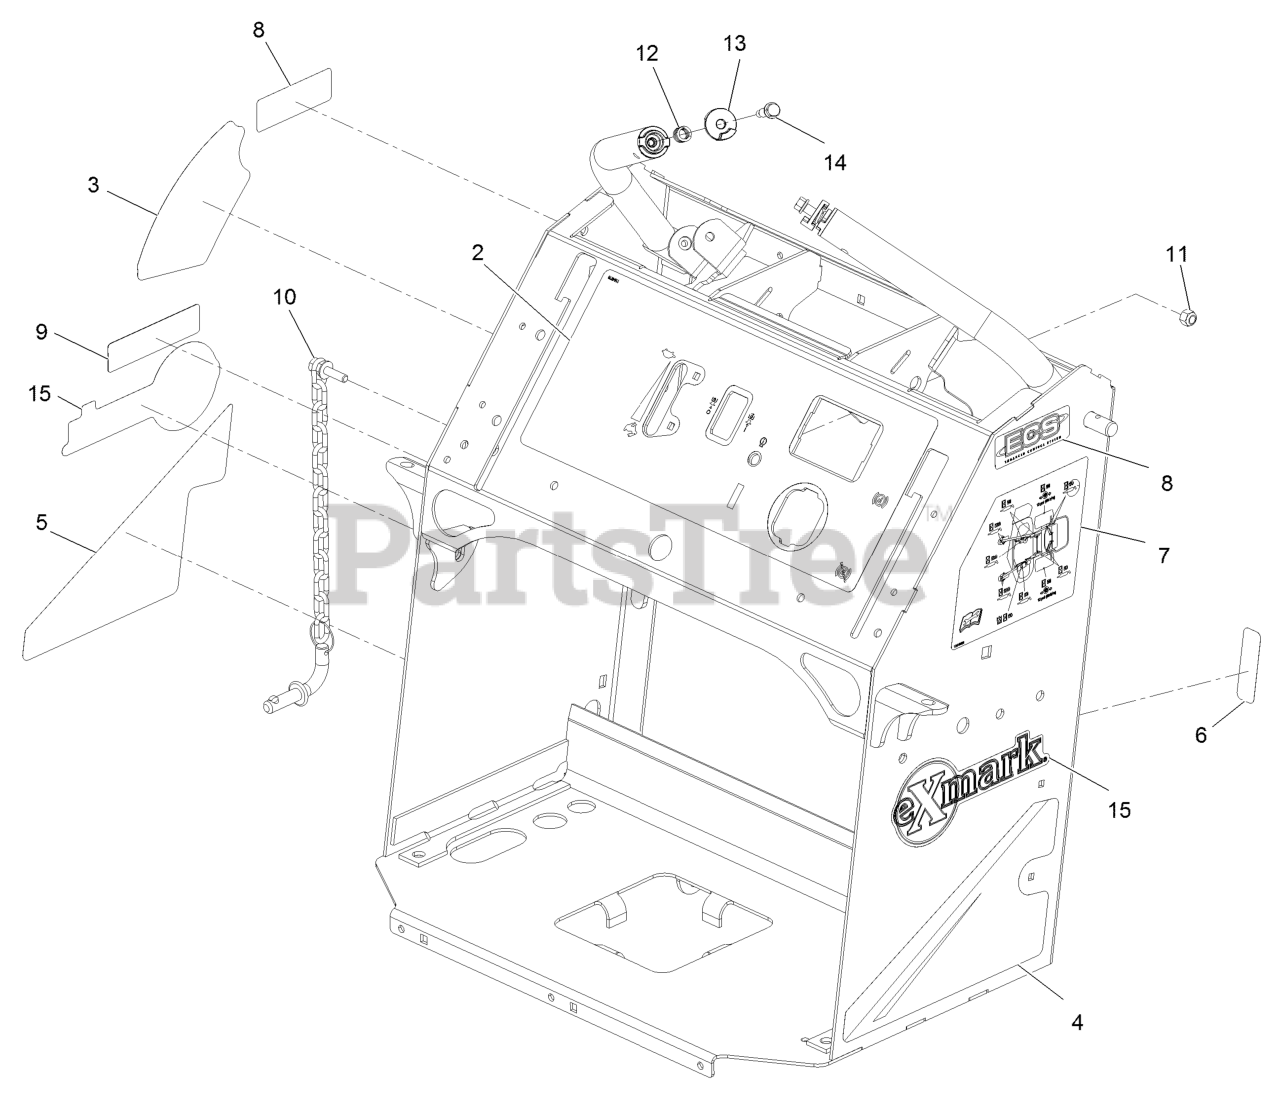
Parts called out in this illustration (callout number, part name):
2	DECAL-CONTROL PANEL EFI
3	DECAL-HEIGHT OF CUT
4	DECAL-LH PANEL
5	DECAL-RH PANEL
6	DECAL-FUSE
7	Decal-Service Aid
8	DECAL-ECS LOGO
9	DECAL-ARRESTER, SPARK
10	HOC PIN ASM
11	NUT-LOCK, NI
12	SPRING-TANK, FUEL
13	LATCH, ECS
14	SCREW-SHOULDER
15	DECAL-EXMARK LOGO
